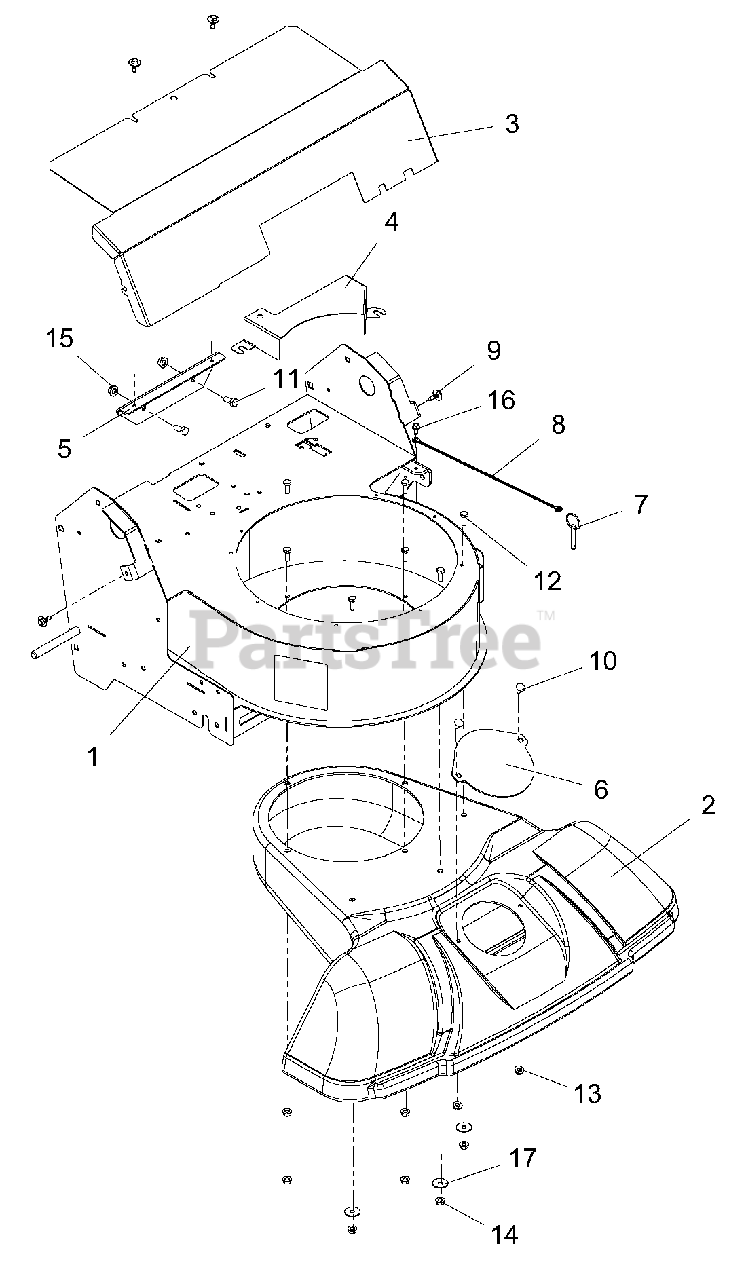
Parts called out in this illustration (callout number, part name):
1	WLDMT, FRAME - APV
2	INLET, UPPER
3	GUARD, TRANS - APV
4	GUARD, BELT - APV
5	BRKT, SUPPORT - TRANS GUARD
6	COVER, HOSE INLET-BLACK
7	PIN, RING DETENT .25 x 1.25
9	SCR, TAP .25-20 x .5 CAPTIVE
10	BLT-RDHDSQSHNK .25-20 x .50 YWZC
11	BLT-HEX .31-18 x .75 GR5 YWZC
12	BLT-HEX .25-20 x .75 GR5 YWZC
13	NUT, LK-CTR-FLG .25-20 YWZC
14	NUT, LK-TOP-FLG .25-20 YWZC
15	NUT, LK-TOP-FLG .312-18 YWZC
16	SCR-TAP .25-20 x .50 HWH TR YWZ
17	WSHR-FL-STL .281 x 1.000 x .063 YWZC
